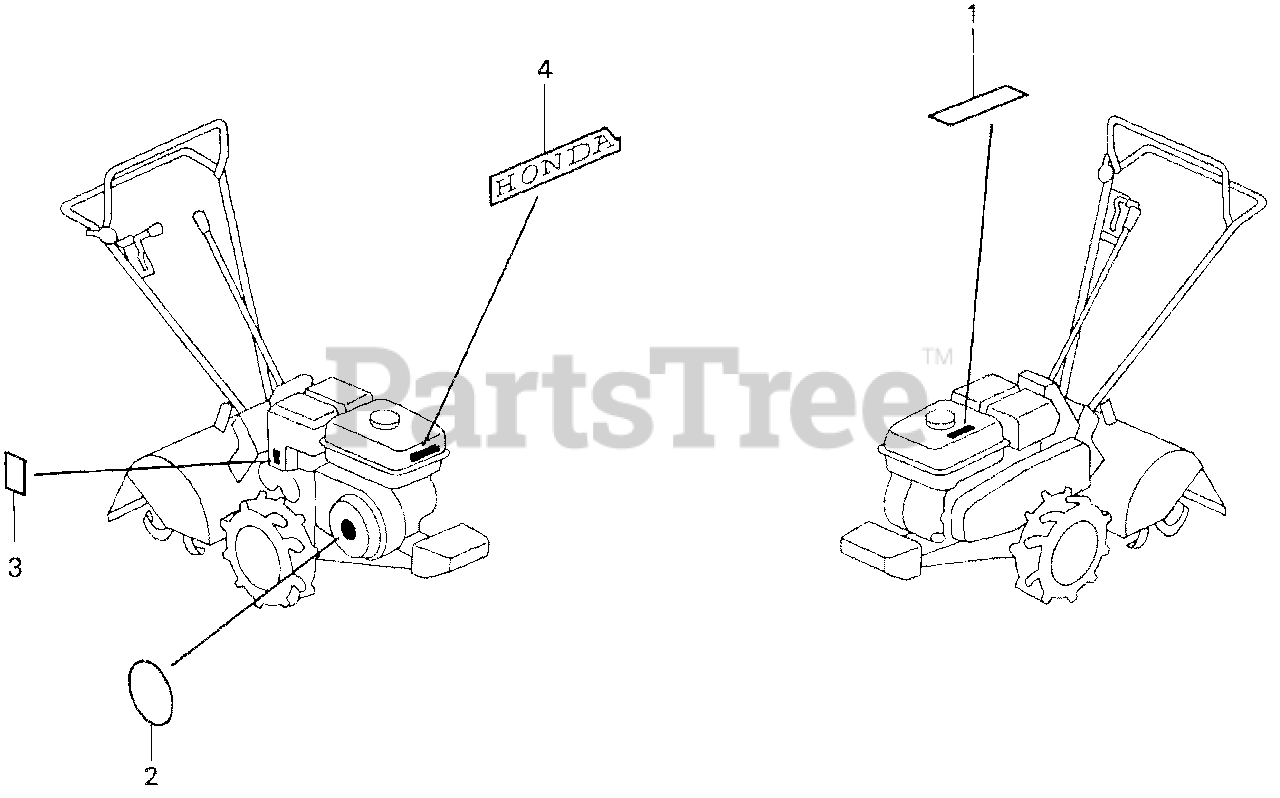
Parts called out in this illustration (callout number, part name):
1	LABEL, OPERATOR WARNING
2	PLATE, EMBLEM
3	MARK, CHOKE
4	MARK, HONDA EMBLEM (120)
